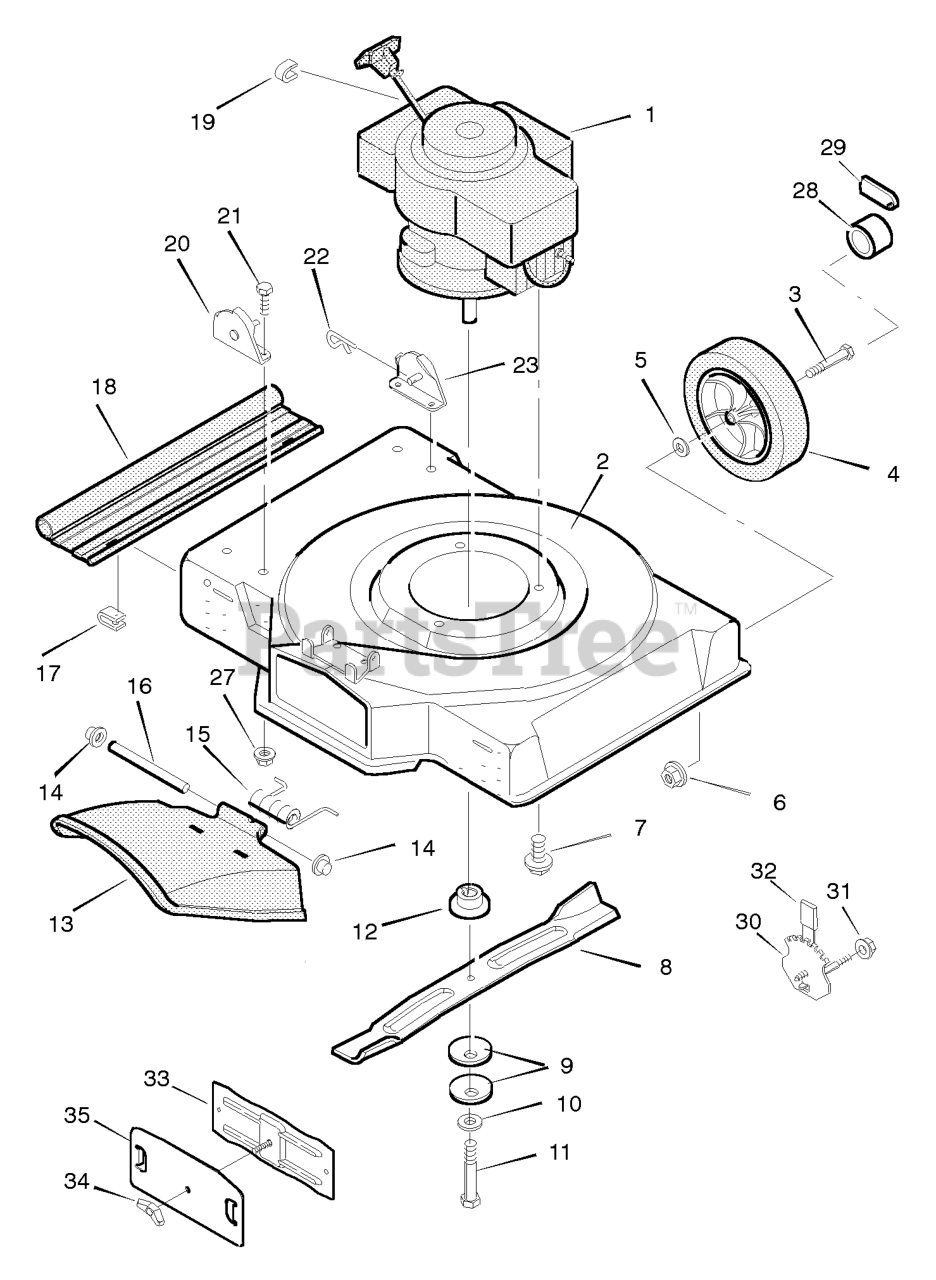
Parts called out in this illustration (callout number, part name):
1	Engine *
2	Housing
3	Bolt, Axle
4	Wheel and Tire *
6	Locknut, Flange
7	Bolt, Engine
9	Washer, Belleville
11	Bolt, Hex
12	Adapter, Blade
13	Deflector, Chute
14	Push- On Cap
16	Pin, Pivot
17	Retainer
18	Deflector, Rear
19	Stop, Rope
20	Bracket, Right Handle
22	Pin, Hair
23	Bracket, Left Handle
27	Nut
28	Hub Cap
29	Hub Cap
30	Adjuster, Height
31	Locknut, Flange
34	Wingnut
